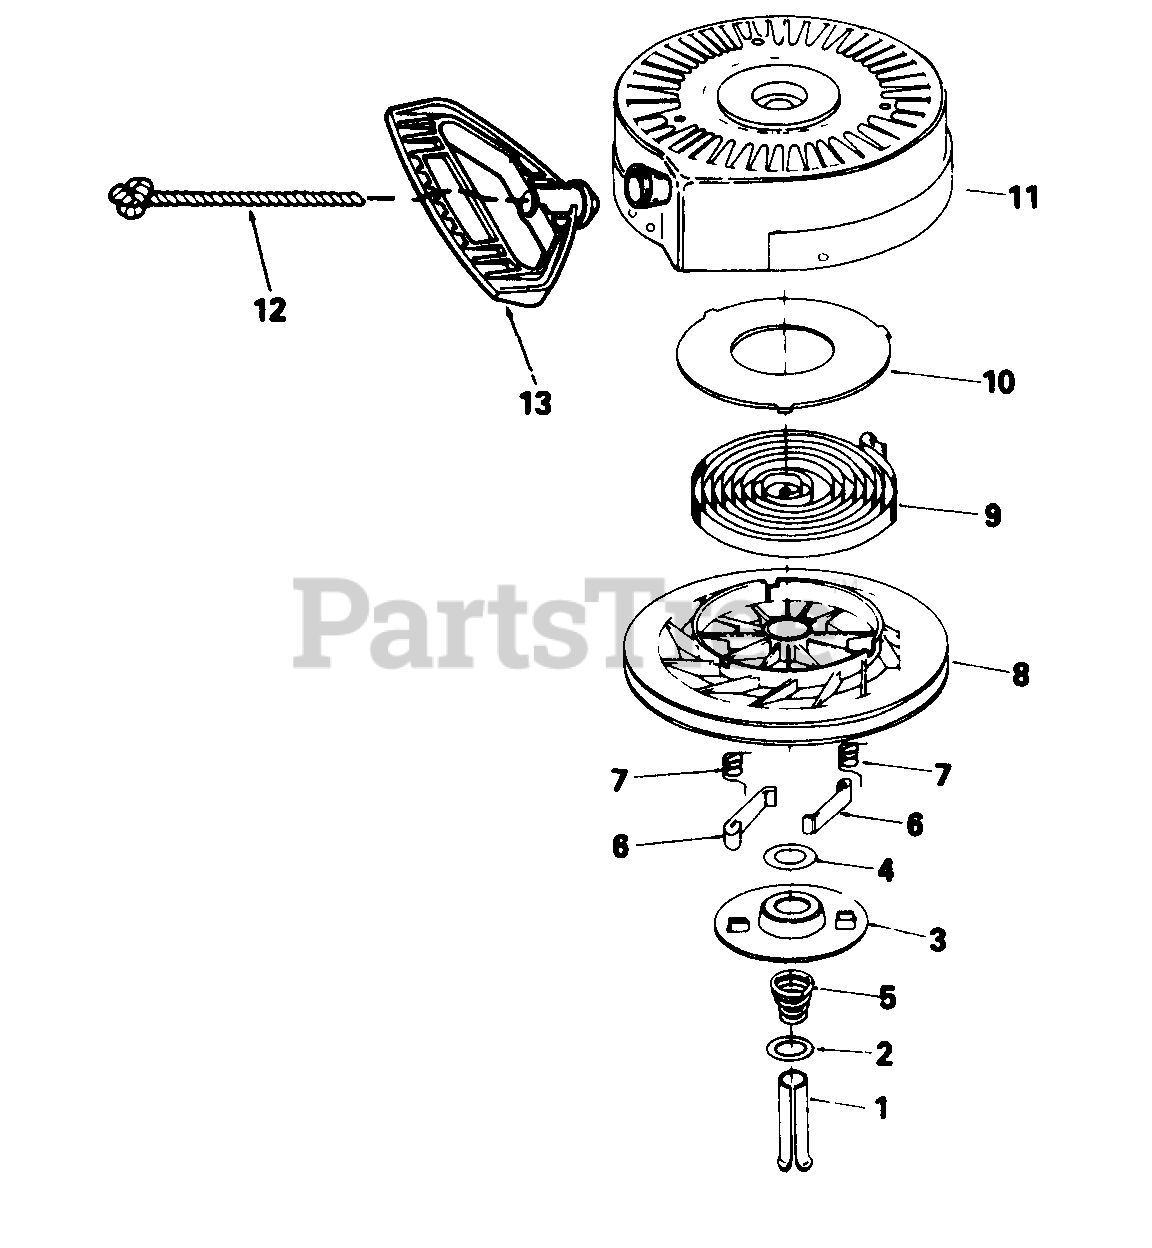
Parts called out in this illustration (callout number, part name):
1	Pin, Spring
5	Spring, Brake
6	Dog, Starter
7	Spring, Dog
8	Pulley
9	Spring, Rewind
10	Cover, Spring
11	Housing Ass'y., Starter
12	Rope, Starter (Length 98" & 9/64" Dia.)
13	Handle, Mitten Grip
